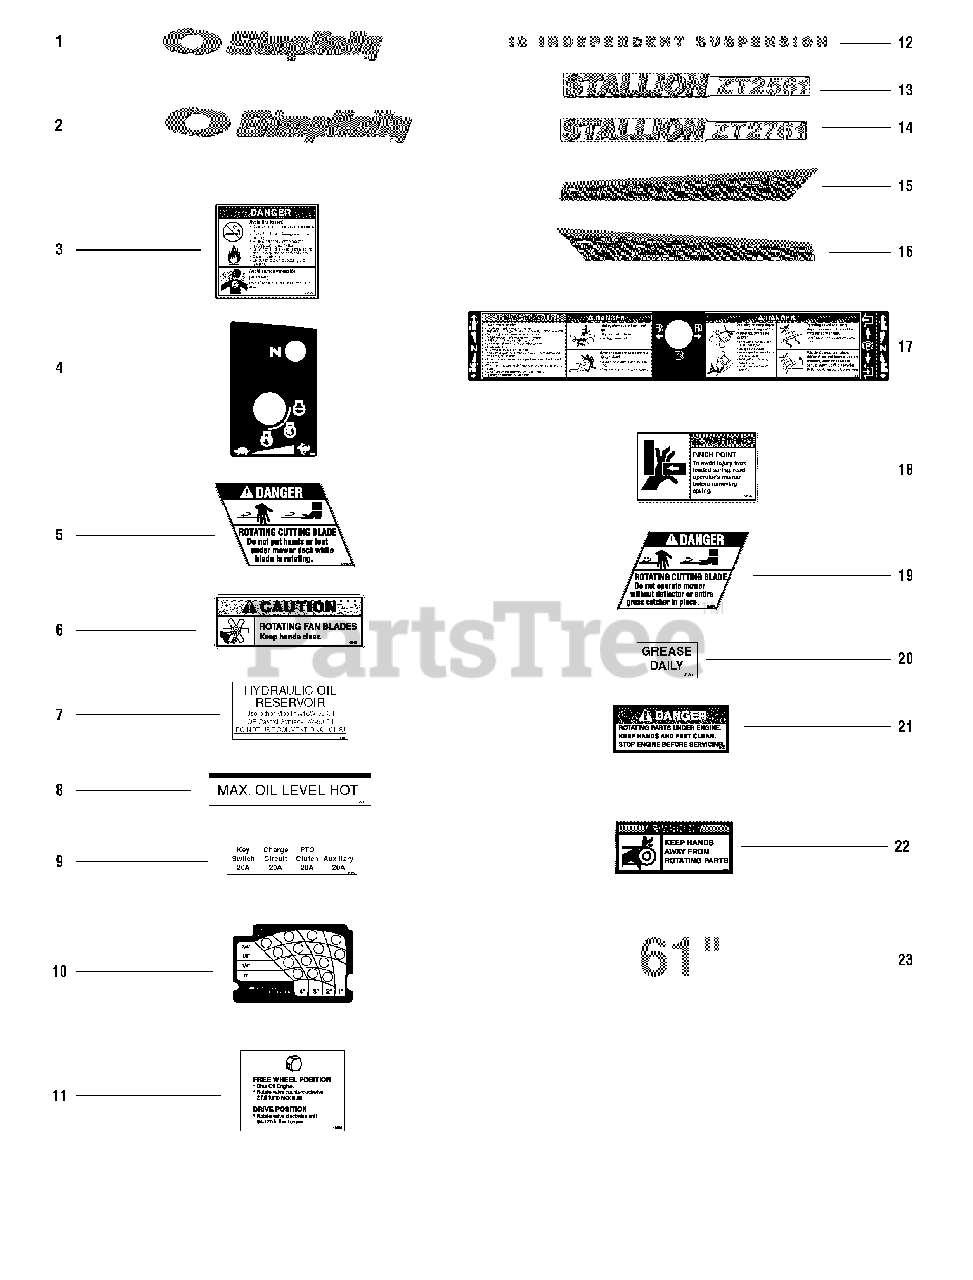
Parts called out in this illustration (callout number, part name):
1	DECAL, Simplicity Logo
2	DECAL, Simplicity Logo
3	DECAL, Danger
4	DECAL, Control Panel
5	DECAL, Danger
6	DECAL, Caution Fan
7	DECAL, Oil Reservoir
8	DECAL, Max. Oil Level
9	DECAL, Fuse Location
10	DECAL, Lift Plate
11	DECAL, Hydro Release Valve
12	DECAL, IS Independent Suspension
13	DECAL, Stallion ZT2561
14	DECAL, Stallion ZT2761
15	DECAL, Stripe-LH
16	DECAL, Stripe-RH
17	DECAL, Main, with Fuel
18	DECAL, Pinch Point
19	DECAL, Danger
20	DECAL, Grease Daily
21	DECAL, Danger Rotating
22	DECAL, Warning
24	DECAL, OPEI CERTIFIED ANSI B71.12003 GOLD
25	DECAL, ID Tag, Serial
